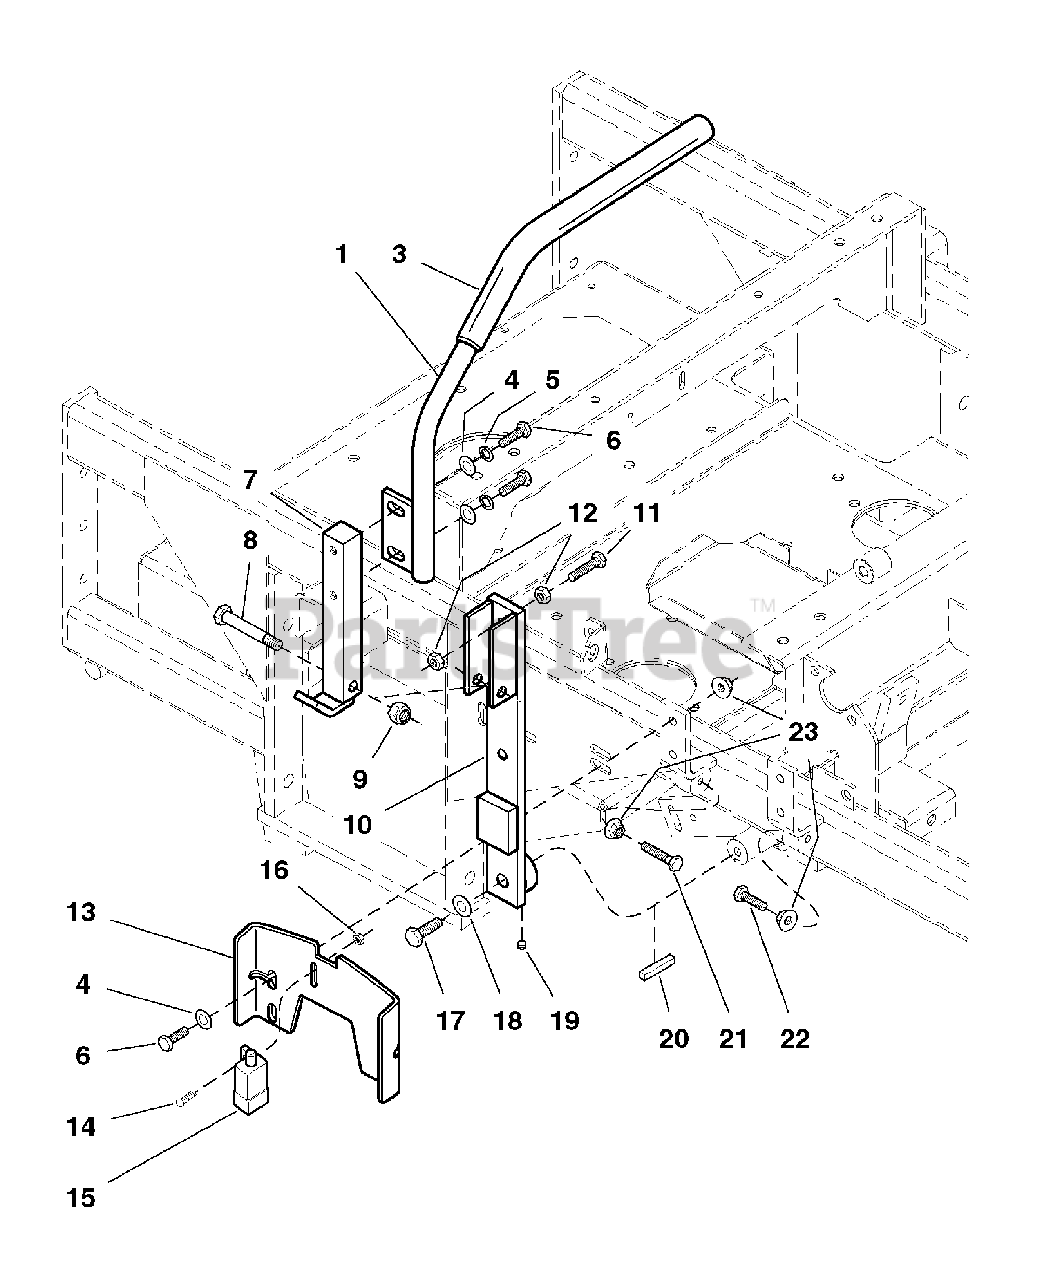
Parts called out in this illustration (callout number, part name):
1	MOTION CONTROL LEVER-RH
4	WASHER, 5/16
5	WASHER, Lock, 5/16
6	CAPSCREW, Hex Hd, 5/16-18 x 3/4
7	CONTROL LEVER BASE
8	CAPSCREW, Hex Hd, 3/8-16 x 2
9	NUT, Hex, Nylon Lock, 3/8-16
10	CONTROL LEVER MOUNT
11	CAPSCREW, Hex Hd, 5/16-18 x 1
12	NUT, Hex, 5/16-18
13	NEUTRAL LOCK PLATE
14	SCREW, #10-24 x 1
15	SWITCH, PLUNGER, N.O./N.C.
16	NUT, Hex, #10-24
17	CAPSCREW, Hex Hd, 3/8-16 x 1-1/4 w/ patch
18	WASHER, 3/8
19	SET SCREW, 5/16-18 x 1/4 w/ patch
20	KEY, 1/4" x 1
21	CAPSCREW, Hex Hd, 5/16-18 x 1-3/4
22	CAPSCREW, Hex Hd, 5/16-18 x 1-1/4
23	NUT, Hex, Serrated Flange, 5/16-18
